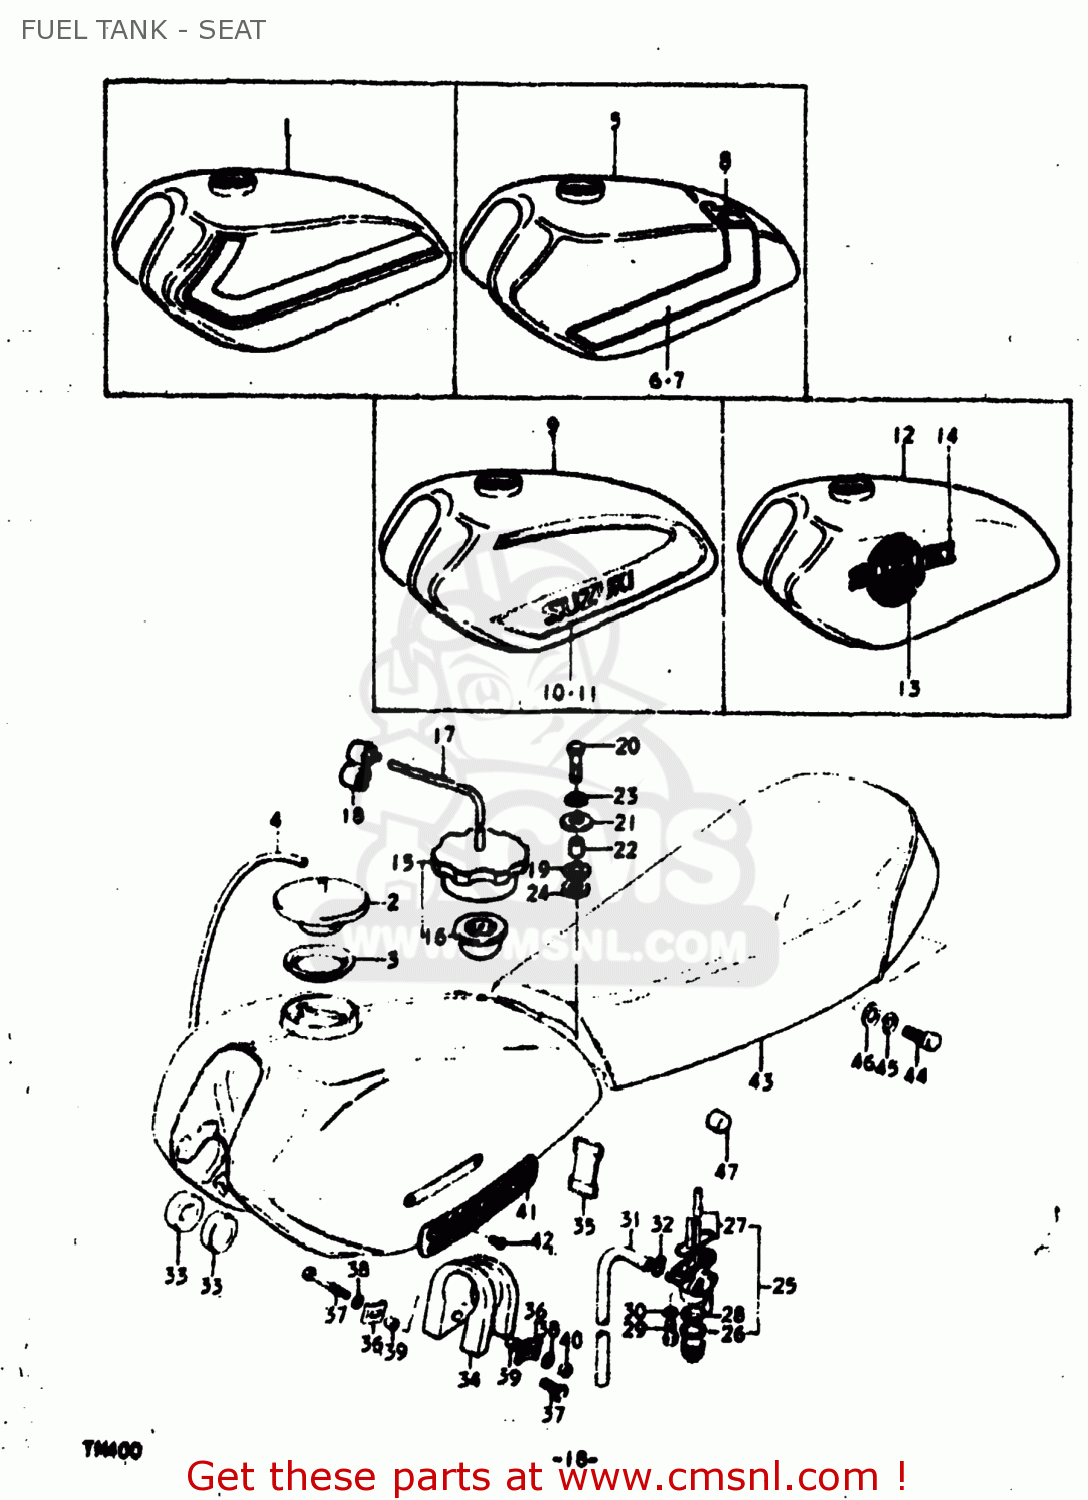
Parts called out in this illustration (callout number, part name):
1	TANK ASSEMBLY,FUEL
2	CAP SET,FUEL TANK
3	GASKET,FUEL TANK CAP (NAS)
4	HOSE
5	TANK ASSEMBLY,FUEL
6	TAPE,FUEL TANK
7	TAPE,FUEL TANK
9	TANK ASSEMBLY,FUEL
10	TAPE,FUEL TANK
11	TAPE,FUEL TANK
12	TANK ASSEMBLY,FUEL
13	TAPE,FUEL TANK
14	EMBLEM
15	CAP ASSY,FUEL TANK FILLER
16	GASKET,FUEL TANK CAP (NAS)
17	HOSE
18	CLAMP,FUEL
19	CUSHION
20	** SUPERSEEDED
21	WASHER
22	SPACER
23	LOCK WASHER
24	CUSHION
25	COCK ASSEMBLY,FUEL
26	GASKET,FILTER (NAS)
27	FILTER SET,FUEL COCK
28	NET,STRAINER
29	SCREW
30	WASHER
31	HOSE
32	CLIP
33	CUSHION
34	CUSHION,FUEL TANK,REAR
35	BAND
36	CLIP
37	BOLT
38	WASHER 6MM
39	SPACER (6.1X8X5.2)
40	NUT
41	EMBLEM
42	SCREW
43	SEAT ASSEMBLY
44	BOLT
45	LOCK WASHER
46	WASHER
47	CUSHION(11.5X22X20)
